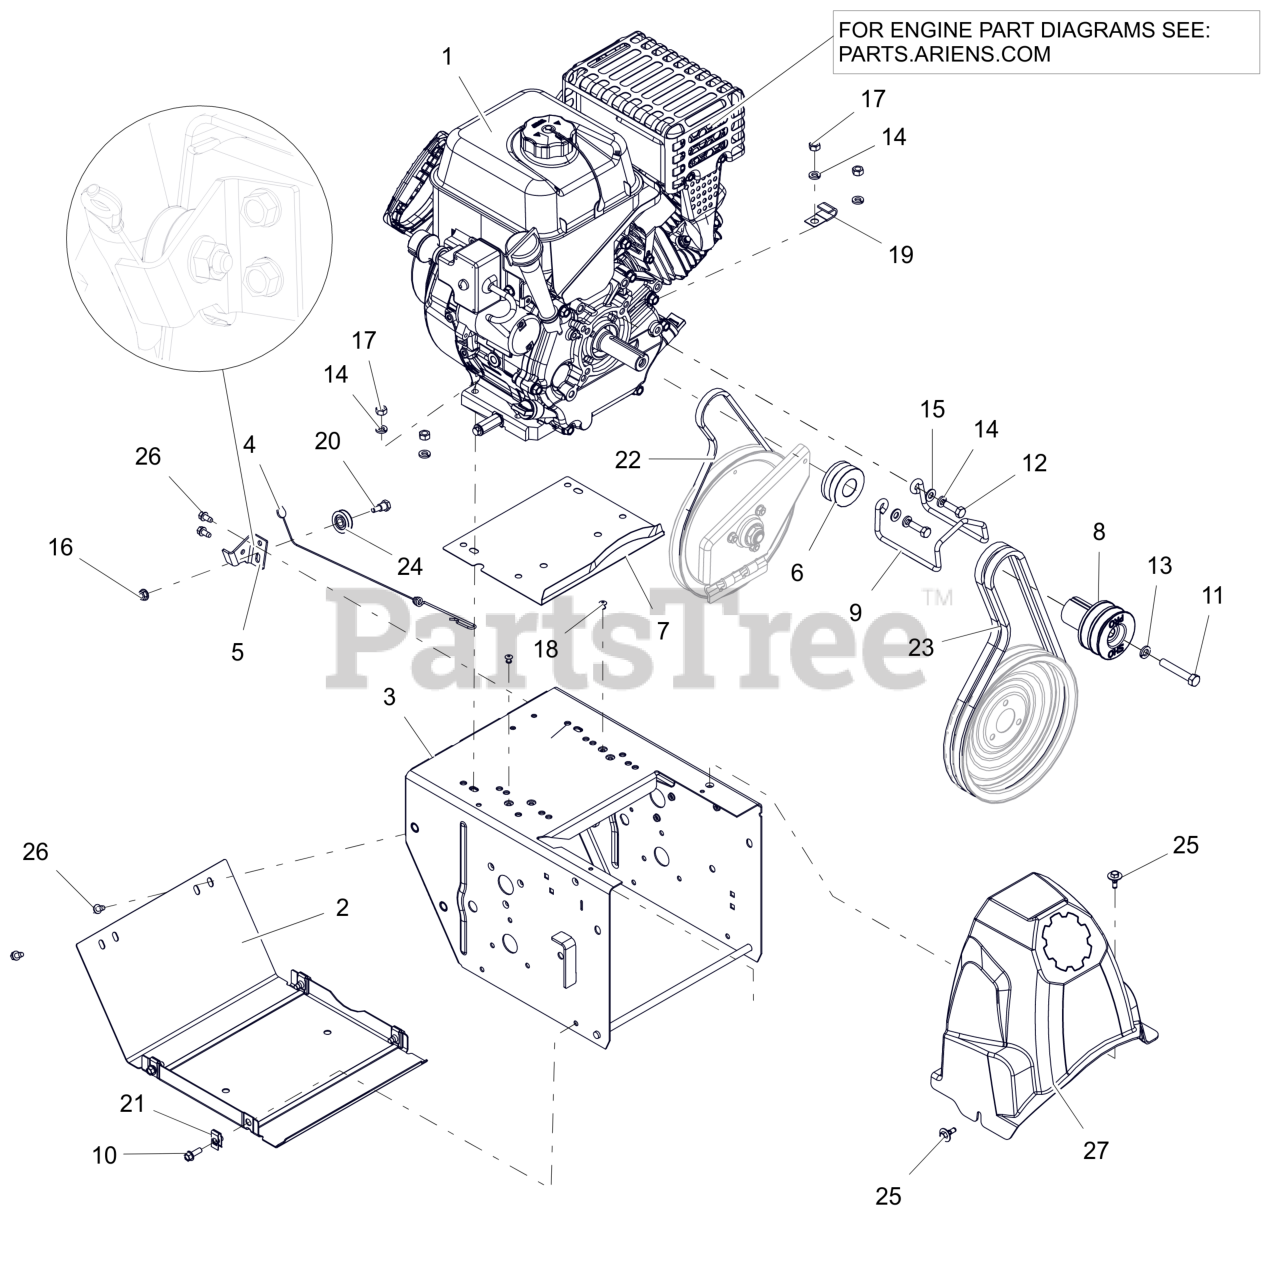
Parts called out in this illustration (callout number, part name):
1	ENGINE, ARIENS AX291 240V/60W
2	COVER, BOTTOM
3	FRAME, MAIN - 14GA DELUXE (ORANGE)
4	CABLE, LOWER TRACTION,SS & PRO
5	BRKT, CABLE PULLEY
6	SHEAVE, TRACTION (KEYLESS)
7	BAFFLE, WATER - LARGE BLOCK
8	SHEAVE,ATTACHMENT-SHO 2 GRV
9	FINGER, BELT
10	BLT, HWH .25-20X.75 G5 ZCC
11	BLT, HEX .38-24X2.25 G5 ZCC
12	BLT, HEX 0.3125-24X1 G5 ZCC
13	WSHR,LK-REG .375X.094 ZCC
14	WSHR, LK-HVY .312X.097 ZCC
15	WSHR,FLT .344X.688X.065 ZCC
16	NUT-LK-TOP-FLG .250-20 GF ZCC
17	NUT, HEX .312-18 ZCC
18	RVT, POP .1875 ZCC
19	J-CLAMP
20	BOLT, SHLDR -.375 X .375 X .25-20
21	NUT-RTNR .25-20X.56
22	V-BELT, 3L-WRAPPED
23	V-BELT, HA-RAW EDGE (SET)
24	PULLEY, CABLE
25	SCR-TAP .25-20X.5 CAPTIVE
26	SCR-TAP .25-20X.50 HWH ZCC
27	COVER, BELT
